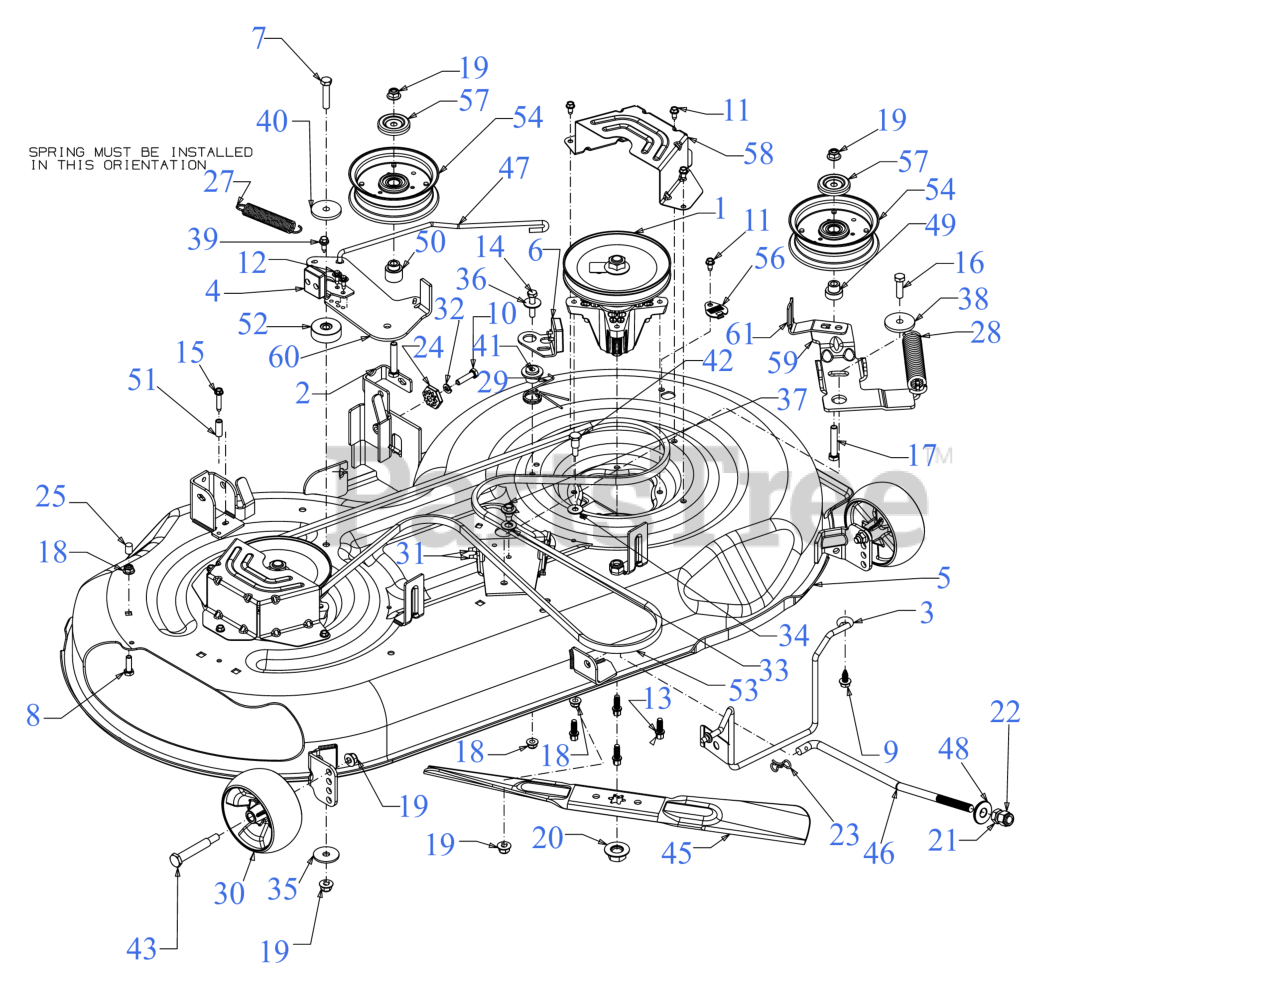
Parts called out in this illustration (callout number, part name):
1	SPINDLE ASSEMBLY-6.74" W/O ZERK
1	Troy-Bilt 46" SPINDLE ASSEMBLY (06989)
4	DECK BRAKE ASSEMBLY (RH)
6	DECK BRAKE ASSEMBLY
7	HEX SCREW 3/8-16 x 1.75 GR5
8	SCREW 5/16-18 x 1.0 GR5
9	SCREW 5/16-18 x .750
10	SCREW 5/16-18 x 1.25 GR5
11	SCREW 1/4-20 X.500
12	SCREW M6-1 x .625
13	SCREW 5/16-18 x .875
14	SCREW 5/16-18 x 1.5 LG
15	SCREW 1/4-20 x 1.25
16	SCREW 3/8-16 x 1.25 GR5
17	SCREW 3/8-16 x 2.0 GR 8
18	FLANGE LOCK NUT 5/16-18
20	HEX NUT
21	HEX JAM NUT 1/2-13
22	HEX LOCK NUT NYLON
23	PIN:COTTER
24	DECK ADJUSTMENT GEAR
25	VINYL CAP
27	EXTENSION SPRING
28	EXTENSION SPRING
29	TORSION SPRING
30	DECK WHEEL
30	WHEELS-DELUXE 5"
31	BUMPER, .62 DIA x .3
32	LOCK WASHER 5/16
33	FLAT WASHER
34	FLAT WASHER
35	FLAT WASHER .406X1.5X11
36	FLAT WASHER 344X1.00
37	SHOULDER SCREW .43X.29X5/16-18 TT
38	SHOULDER SPACER
39	SHOULDER SCREW
40	SHOULDER SPACER
41	DOUBLE SHOULDER SPACER .750 x .135
42	SHOULDER SCREW
43	SHOULDER BOLT .50 x 2.5 x 3/8 -16
45	23.25" BLADE (2N1)
45	Genuine Factory Parts 46" BLADE SET(STAR
45	46" 6 PT STAR LOW LIFT/SAND BLADE
45	Cub Cadet 46" LOWLIFT BLADE SET
45	Genuine Factory Parts 46" LOWLIFT BLADE SET
45	23.25" BLADE (2N1) (XTREME)
45	Cub Cadet BLADE SET (XTREME) 46" CUB 04290-X
46	DECK FRONT LIFT ROD
47	DECK BRAKE ROD
48	DECK LIFT PIVOT CUP
49	SHOULDER SPACER
50	SHOULDER SPACER
51	SPACER
52	SPACER .385ID x 1.75OD x .585THK
53	V-BELT A SEC x 103.24
53	Genuine Factory Parts 46" DECK DRIVE BELT
54	IDLER PULLEY 4.50" DIA
56	DECK WASH PLUG
57	IDLER PULLEY CAP
59	IDLER BRACKET 46T (LH)
60	DECK IDLER BRACKET
